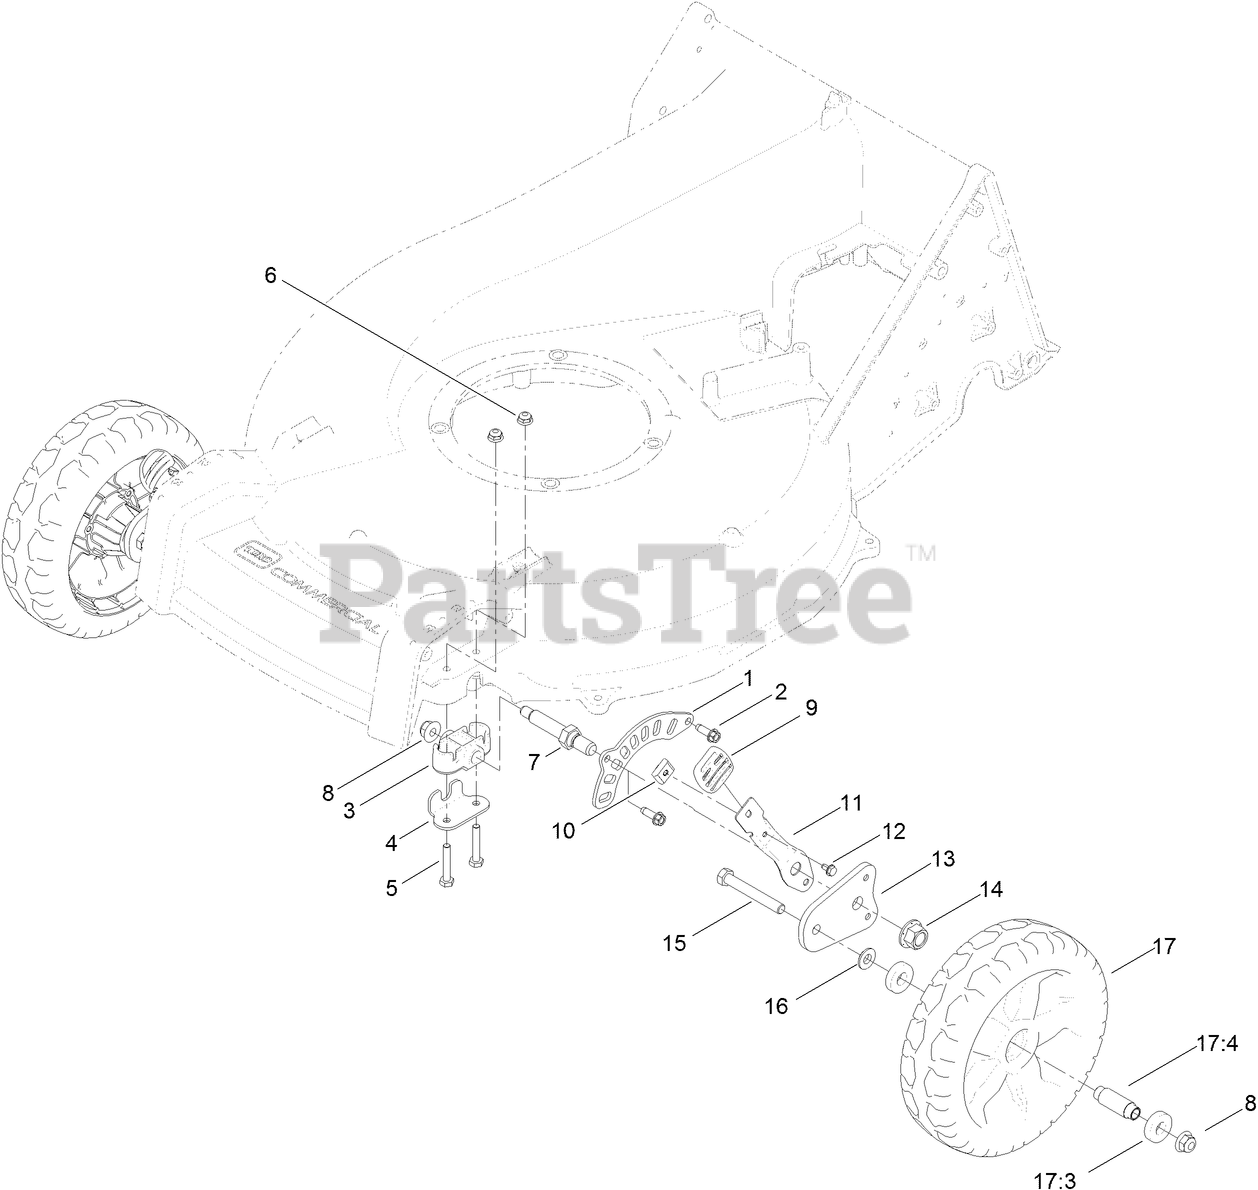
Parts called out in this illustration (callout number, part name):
1	PLATE-HOC, FRONT
2	SCREW-HWHTF
3	BUSHING-AXLE, FRONT HOC
5	SCREW-HH
6	NUT-HF
8	NUT-HF, NI
9	KNOB-LEVER, HOC
10	KEY-ARM, SPRING
11	ARM-SPRING
12	SCREW-HWH
13	ARM-PIVOT, FRONT
14	NUT-LOCK
15	SCREW-HH
16	SPACER-COVER, WHEEL
17:3	BEARING-WHEEL
17:4	SPACER
